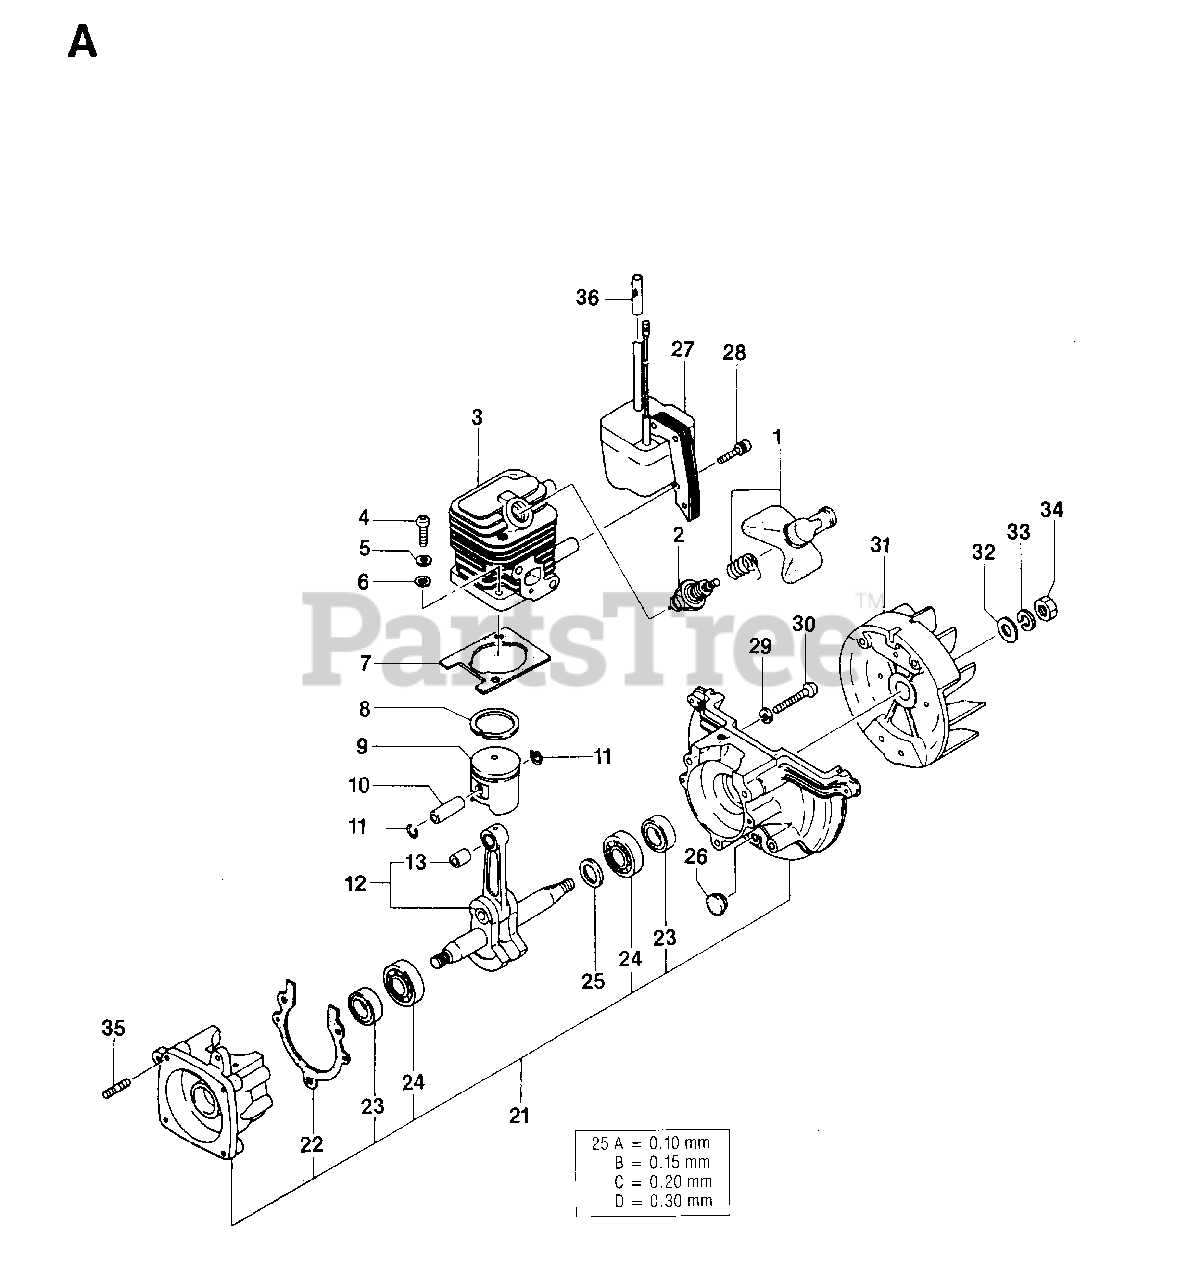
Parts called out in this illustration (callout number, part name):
2	SPARK PLUG CJ8 NLA
4	SCREW MC6S 5X20
5	SPRING WASHER
6	WASHER
29	SPRING WASHER
30	SCREW MC6S 5X30
32	WASHER BRB 8.4X17
33	SPRING WASHER
34	NUT
